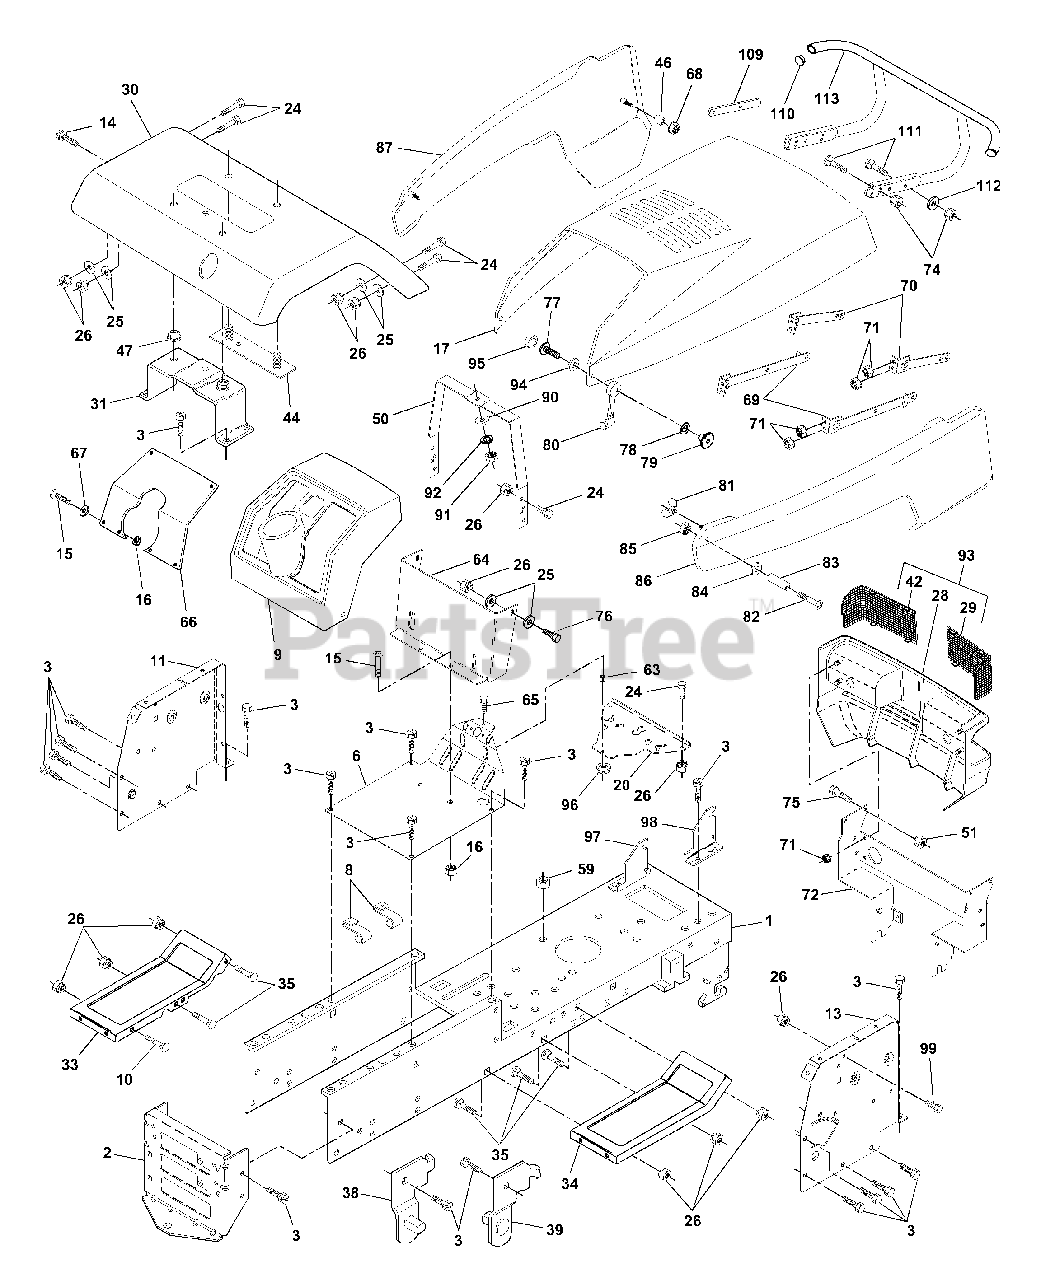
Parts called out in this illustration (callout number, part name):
1	Chassis
2	Drawbar
3	Screw, Thd., Roll. 3/8-16 x 3/4
8	Clip, Insulator
10	Bolt, Carriage 3/8-16 UNC x 1
11	Dash Panel, LH
13	Dash Panel, RH
14	Screw, Thd., Roll. 3/8-16 x 1/2
15	Screw, Machine 5/16-18 UNC x 3/4
16	Nut, Hex, Keps 5/16-18 UNC
20	Plate, Battery Support
24	Bolt, Fin Hex 3/8-16 x 1 Gr. 5
25	Washer 13/32 x 13/16 x 12 Gauge
26	Nut, Lock, Hex W/Ins 3/8-16 UNC
28	Grille
29	Lens, Headlight, RH, Smoked
30	Fender
31	Bracket Fender
33	Footrest, LH
34	Footrest, RH
35	Bolt, Carriage 3/8-16 x 3/4
38	Pivot Bracket Assembly, Rear, LH
39	Pivot Bracket Assembly, Rear, RH
42	Lens, Headlight, LH, Smoked
44	Strap, Fender
47	Nut, Push, Nylon
50	Support, Dash
51	Nut, Lock W/Ins. 1/4-20 UNC
59	Bushing, Snap Split
63	Spacer, Split
64	Dash, Lower
65	Bolt, Hex, Fin. 5/16-18 UNC x 2
66	Plate, Dash
67	Washer 11/32 x 11/16 x 16 Gauge
68	Nut, Hex, Keps 1/4-20 UNC
69	Strap Assembly, Hinge, Rear
70	Strap Assembly, Hinge, Front
71	Nut, Keps Blk Hex 1/4-20 UNC
72	Support Assembly, Grille
74	Nut, Crownlock 3/8-16 UNC
75	Bolt, Shoulder 1/4-20 UNC
76	Bolt, Fin Hex 3/8-16 UNC x 1-1/4
77	Screw, Machine, Cross Pan Head #10-24 x 1/2
78	Washer, Lock #10
79	Nut, Weld
80	Latch, Chute
81	Wing Nut, Plastic 1/4-20
82	Screw, Machine, Cross Pan Head #10-24 x 1-1/4
83	Spacer, Split #10 x 3/4
84	Washer 7/32 x 1/2 x 18 Gauge
85	Nut, Hex, Keps #10-24 UNC
86	Side Panel, RH
87	Side Panel, LH
90	Washer 9/32 x 3/4 x 16 Gauge
91	Nut, Hex, Fin. 1/4-20 UNC
92	Washer, Lock, Hvy Hlcl 1/4
93	Grill Assembly
94	Washer, Cap
95	Cap, Black
96	Nut, Lock, Hex w/Ins. 5/16-18
97	Pivot Bracket Assembly, LH
98	Pivot Bracket Assembly, RH
99	Bolt, Hex, Fin. 3/8-16 x 1
109	Bracket, Ext. Bumper
110	Plug, Plastic
111	Bolt, Carriage 3/8-16 x 1-1/4
112	Washer 13/32 x 13/16 x 16 Ga.
113	Bumper Assembly
